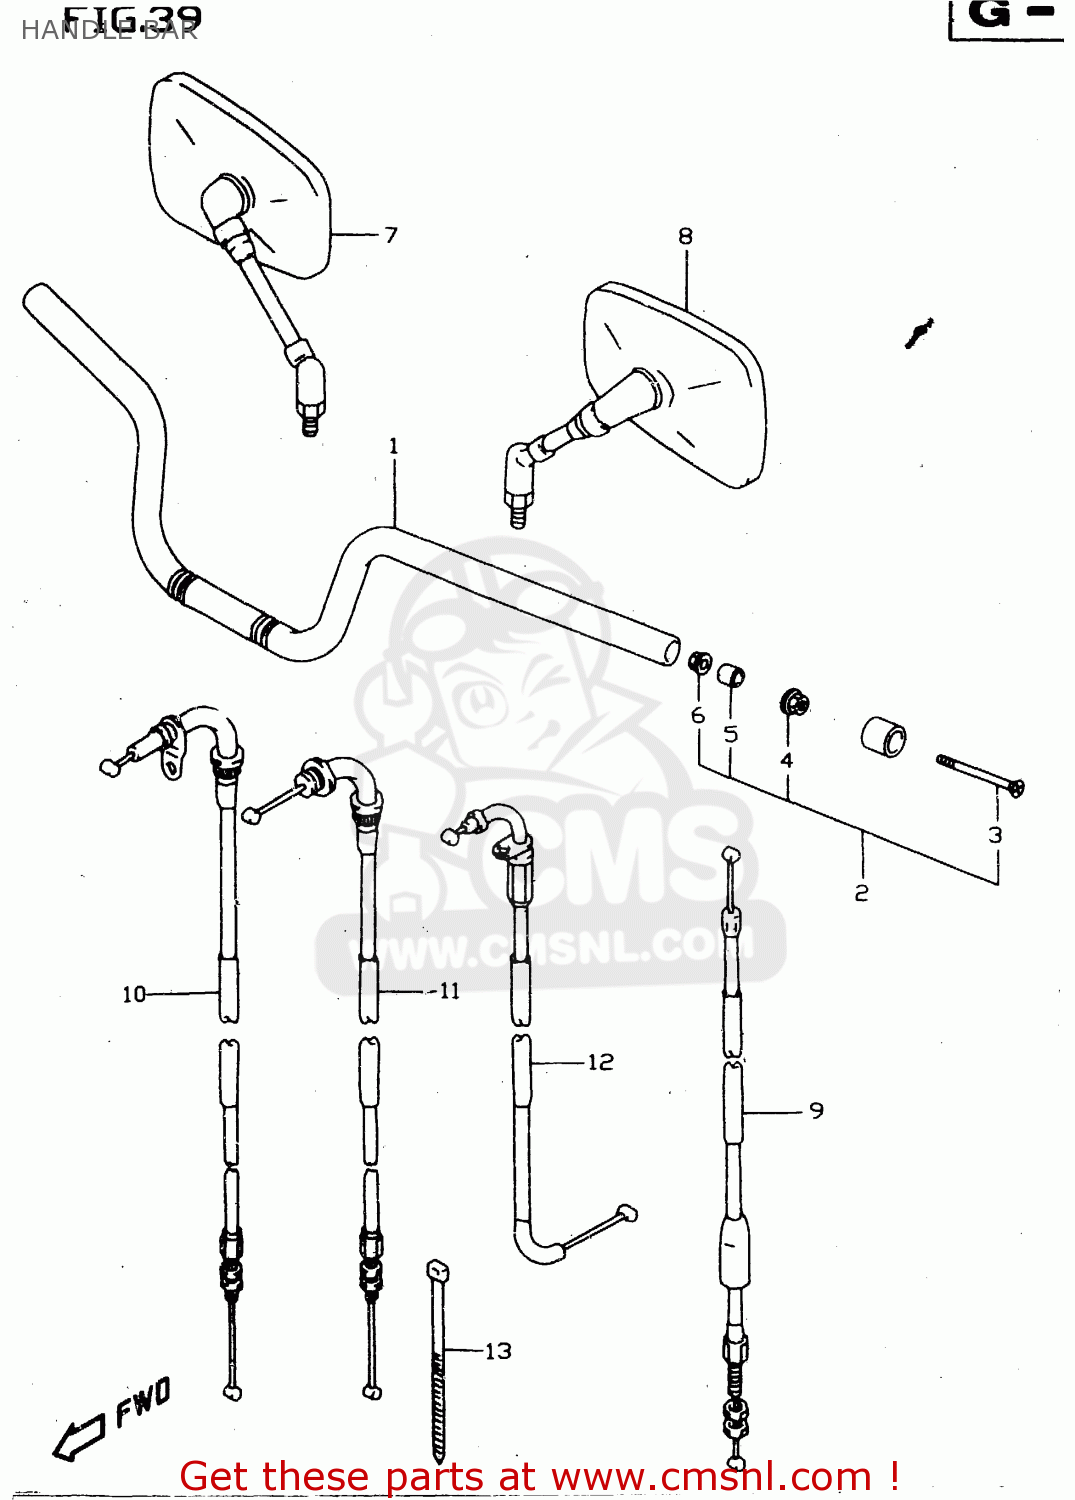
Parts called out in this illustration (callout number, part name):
1	HANDLEBAR
2	BALANCER SET,HANDLEBAR
3	SCREW
4	NUT
5	EXPANDER,HANDLE BALANCER
6	NUT
7	MIRROR ASSY,RR VIEW,R
8	MIRROR ASSY,RR VIEW,L
9	CABLE ASSY,CLUTCH
10	CABLE ASSY,THROTTLE NO.1
11	CABLE ASSY,THROTTLE NO.2
12	CABLE,STARTER
13	CLAMP(L:235)
